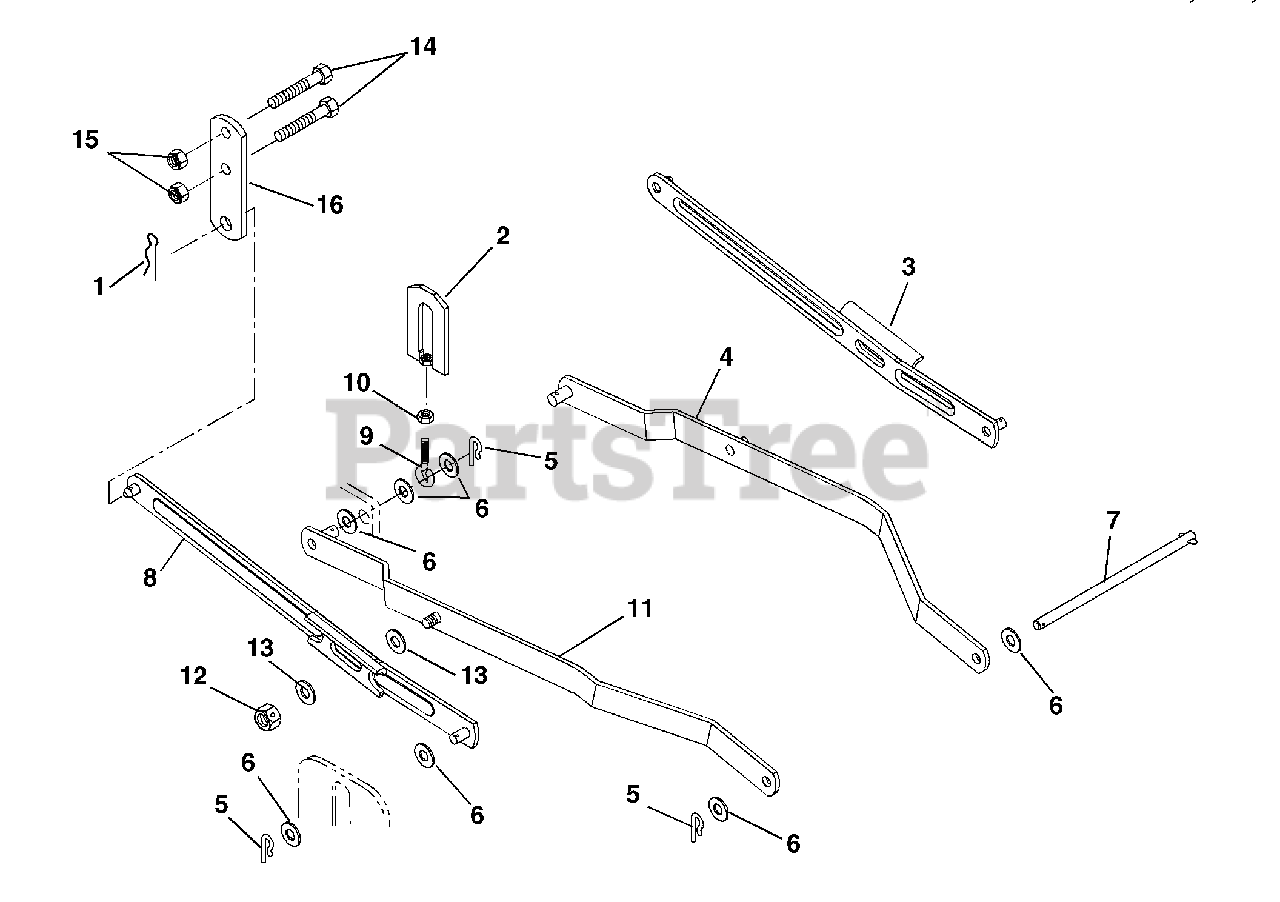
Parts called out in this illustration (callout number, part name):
1	PIN-HAIR-EXT .12X.31X2.37 YWZC
2	LINK, ADJUSTMENT
2	LINK, ADJUSTER
3	HANGER, REAR LH
4	ARM, LIFT LH
5	CLIP, SPRING
5	HANGER, REAR RH
6	@WSHR-FL-STL.531X1.06X.095YWZC
8	HANGER, REAR RH
9	HANGER
9	BLT-EYE .375-16X2.50 YWZC
10	NUT-HEX-JAM .375-16 YWZC
11	ARM, LIFT RH
12	@NUT-LK-CTR .62-11 YWZC
13	@WSHR-FL-STL.656X1.31X.095 YWZ
14	@BLT-HEX .38-16X.75 GR5 YWZC
15	@NUT-LK-TOP-FLG .38-16 YWZC
16	HANGER BRACKET
